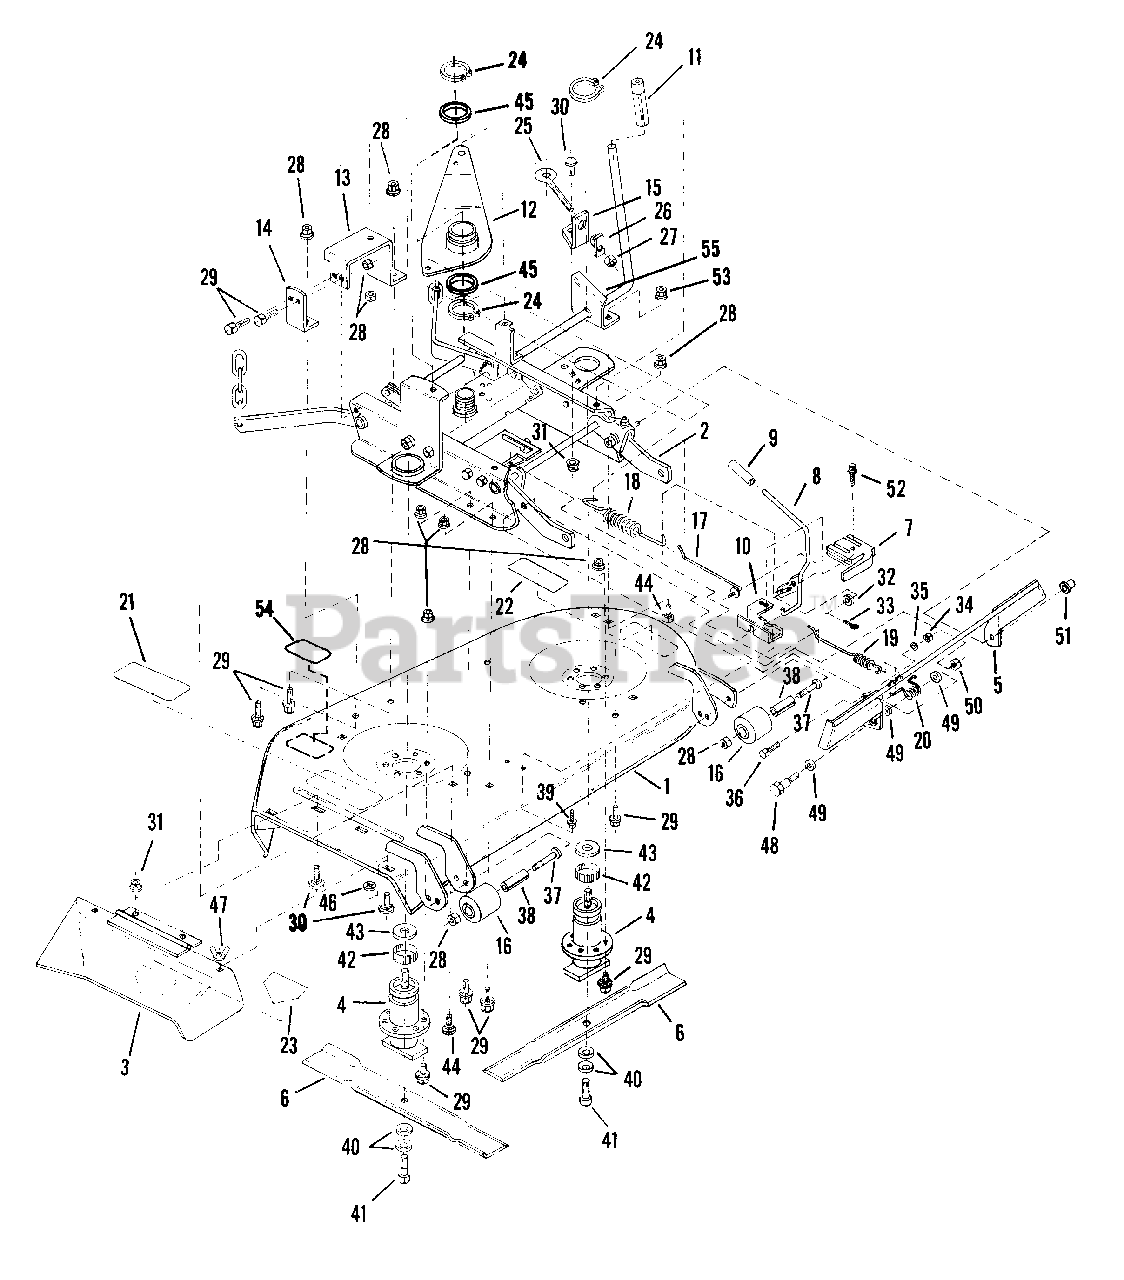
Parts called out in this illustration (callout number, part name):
1	ASSEMBLY, Deck
2	ASSEMBLY, Rail
3	ASSEMBLY, Side Chute
4	ASSEMBLY, Spindle
5	ASSEMBLY, Pedal
6	BLADE, 21"
7	SWITCH
8	ENGAGE LEVER
9	GRIP, Handle
10	BRACKET
11	GRIP, Lever
12	IDLER ARM
13	SUPPORT, Idler
14	BRACKET
15	ANCHOR
16	ROLLER
17	ROD, Idler
18	SPRING, Belt
19	SPRING, Latch
20	SPRING, Pedal
21	DECAL, Caution (Rotating Blades)
22	DECAL, Caution (Rotating Blades)
23	DECAL, Danger (Keep Hands & Feet Away)
24	RING, 2" External Retaining
25	EYE-BOLT
26	T-NUT
27	NUT, 1/4 Hex
28	NUT, Lock 3/8-24
29	CAPSCREW, 3/8-24x3/4" Hex Head
30	CARRIAGE BOLT, 5/16-18
31	LOCKNUT, Hex Flange 5/16-18
32	WASHER, 1/4 SAE
33	PIN, Cotter 3/32x3/4
34	NUT, 1/4-28 HEX
35	WASHER, Lock Internal Tooth 1/4
36	CAPSCREW, 1/4-28x1" Hex Head
37	CAPSCREW, 3/8-24x3 3/4" Hex Head
38	SPACER
39	SCREW, Self Tapping 1/4-20x5/8
40	WASHER, Cone
41	CAPSCREW, 3/8-24x1" Hex Head
42	RING, Tolerance
44	CARRIAGE BOLT, 3/8-16x3/4"
45	WASHER, 2" I.D.
46	RETAINER, Bolt 5/16
47	WINGNUT, 5/16-18
48	BOLT, Shoulder 3/8-24x1 3/4
49	WASHER, 1/2 SAE
50	NUT, Hex 3/8-24
51	NUT, Push 1/2"
52	SCREW, Self Tapping #10x1"
53	NUT, 3/8-16 Hex Lock
54	PLATE, Model Number
55	BRACKET, Height Indicator
